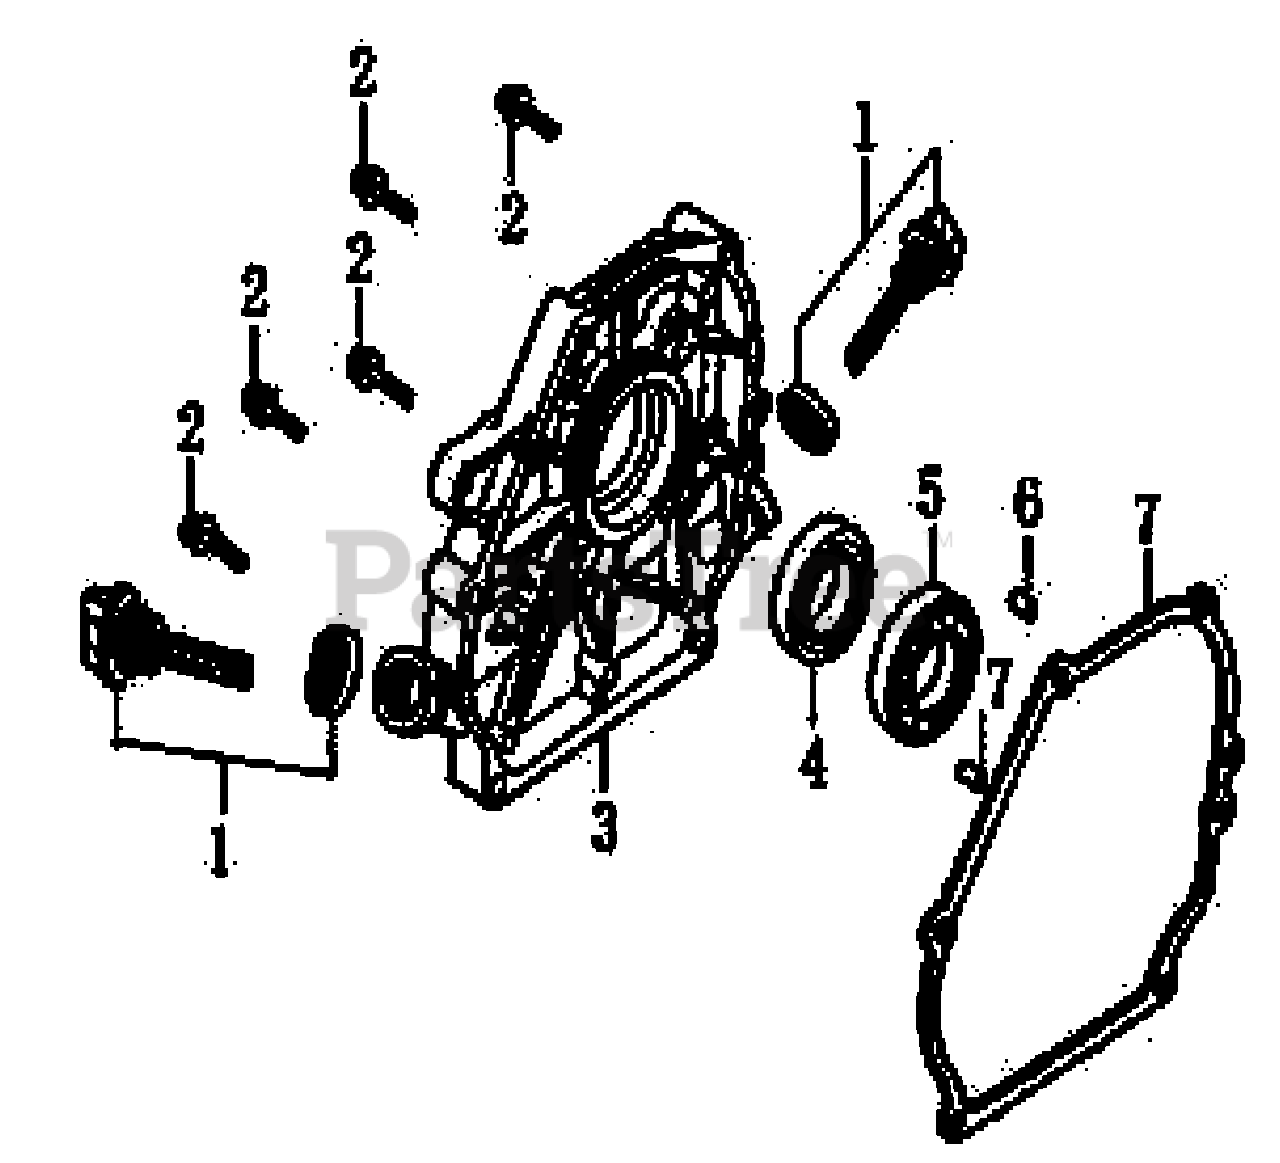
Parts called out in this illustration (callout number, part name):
1	DIPSTICK WITH WASHER
2	BOLT, FLANGE
3	COVER, CASE
4	SEAL, OIL SEAL 25X41.25X6
5	BEARING, RADIAL BALL
6	PIN, DOWEL
7	GASKET, CASE COVER
